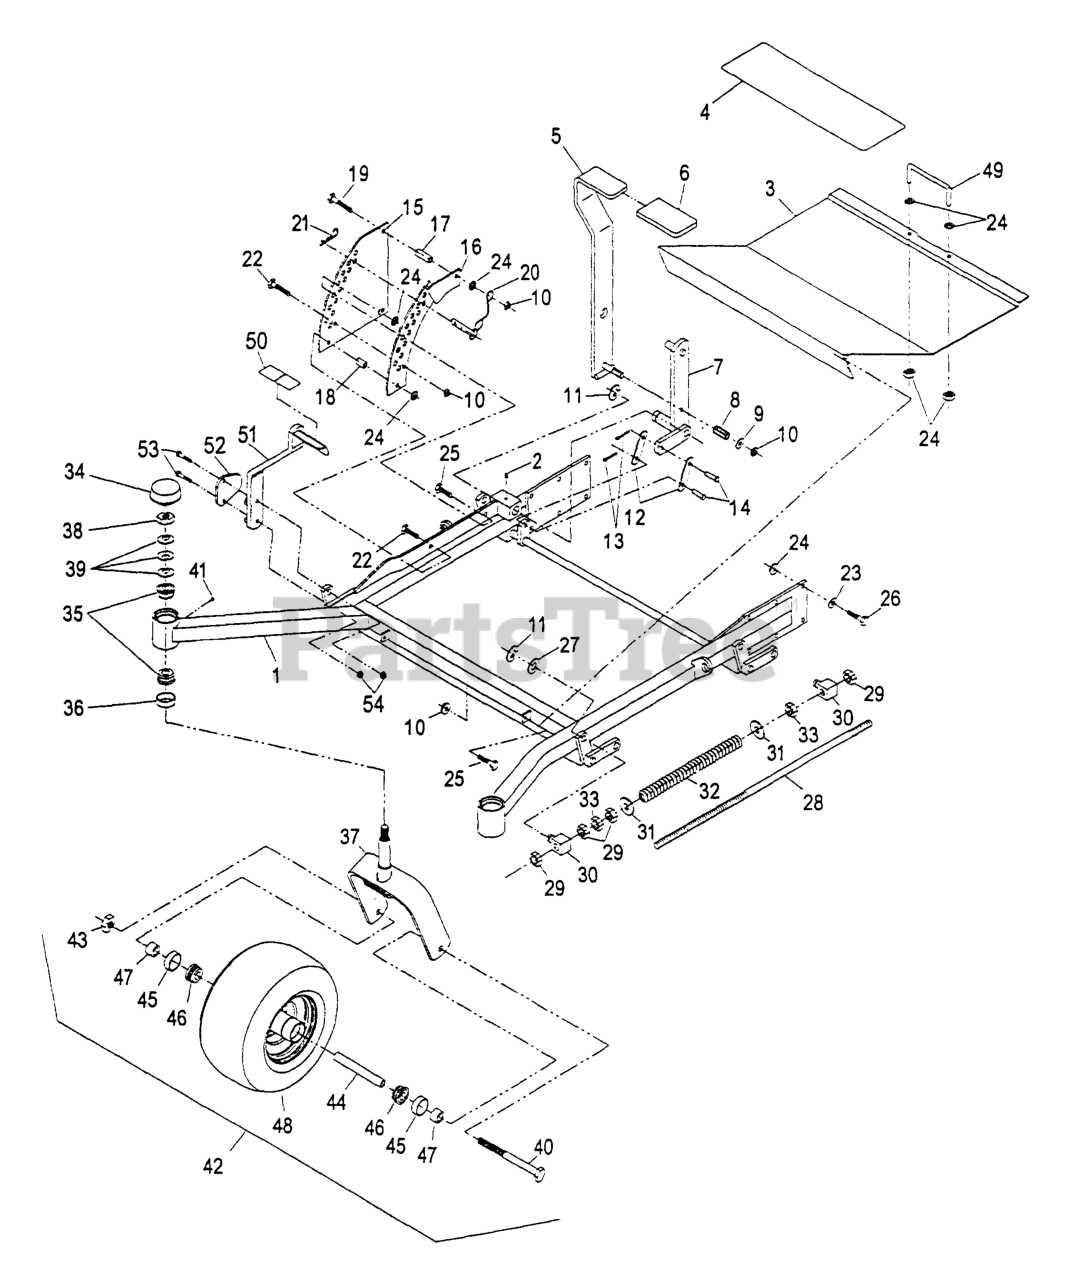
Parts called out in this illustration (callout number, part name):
4	PAD-ANTISKID
6	GRIP-LEVER, LIFT
8	SPRING-COMPRESSION
12	ARM-LIFT, DECK
14	PIN-CLEVIS
15	PLATE-LIFT, DECK
16	PLATE-LIFT, DECK
17	BUSHING-LEVER, LIFT
18	BUSHING-LEVER, LIFT
20	PIN-HITCH (W/LANYARD)
21	PIN-COTTER
28	ROD-LIFT, DECK
30	SWIVEL-DECK MOUNT, REAR
32	SPRING-SUPPORT, DECK
34	CAP-GREASE
35	Cone-Bearing Tapered Roller
36	SEAL-GREASE
39	WASHER-BELLVILLE
42	CASTER WHEEL ASM
44	SPACER-CASTER, FRONT
45	SEAL-BEARING
46	BEARING-CONE, TAPERED ROLLER
47	SPACER-BEARING
48	WHEEL AND TIRE ASM
49	HANDLE,DECK
52	STRAP
